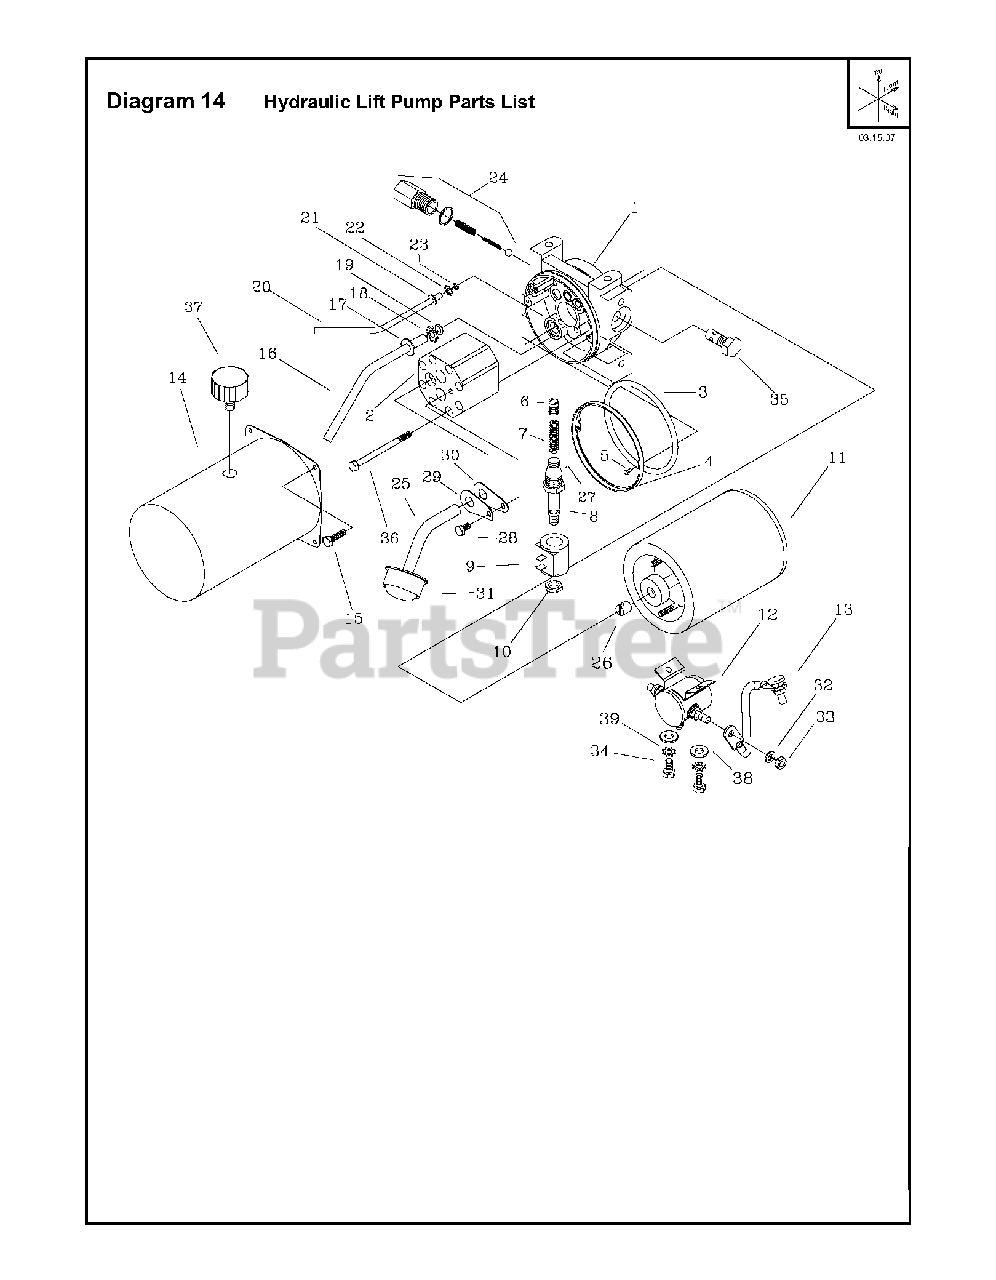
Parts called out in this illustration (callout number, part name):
2	FS900T PPE HYDRAULIQUE/
11	DRUCKBEGRENZUNGSVENTIL
15	TBDMach. Screw, Washer Hd 1/4" - 20 x 1/2"
24	FS900T KIT RELIEF VALVE/
26	FS900T BOUTON CLAVETTE/
32	LOCKWASHER. SPLIT .3125 (M8)
39	TBDWasher, Star External, 3/8"
